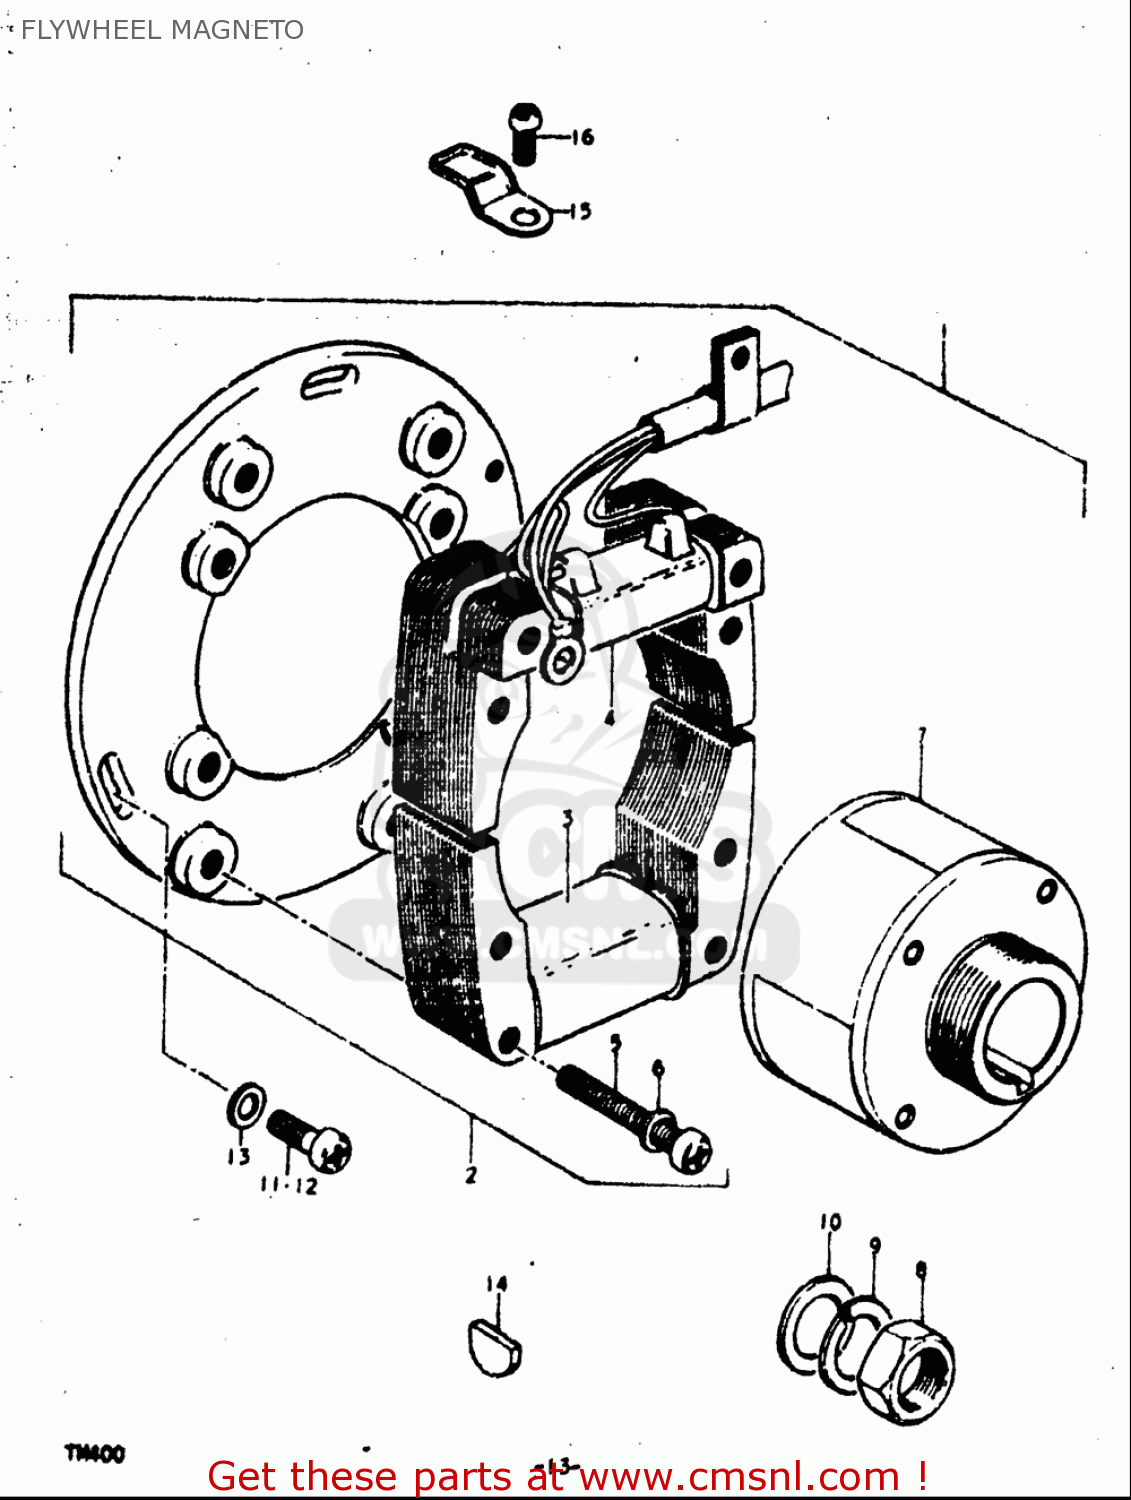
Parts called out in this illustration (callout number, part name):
5	SCREW
6	WASHER,LOCK
8	NUT
9	WASHER,LOCK
10	WASHER(14X27X3)
11	SCREW
12	SCREW(5X14)
13	WASHER
14	KEY
15	CLAMP
16	SCREW
